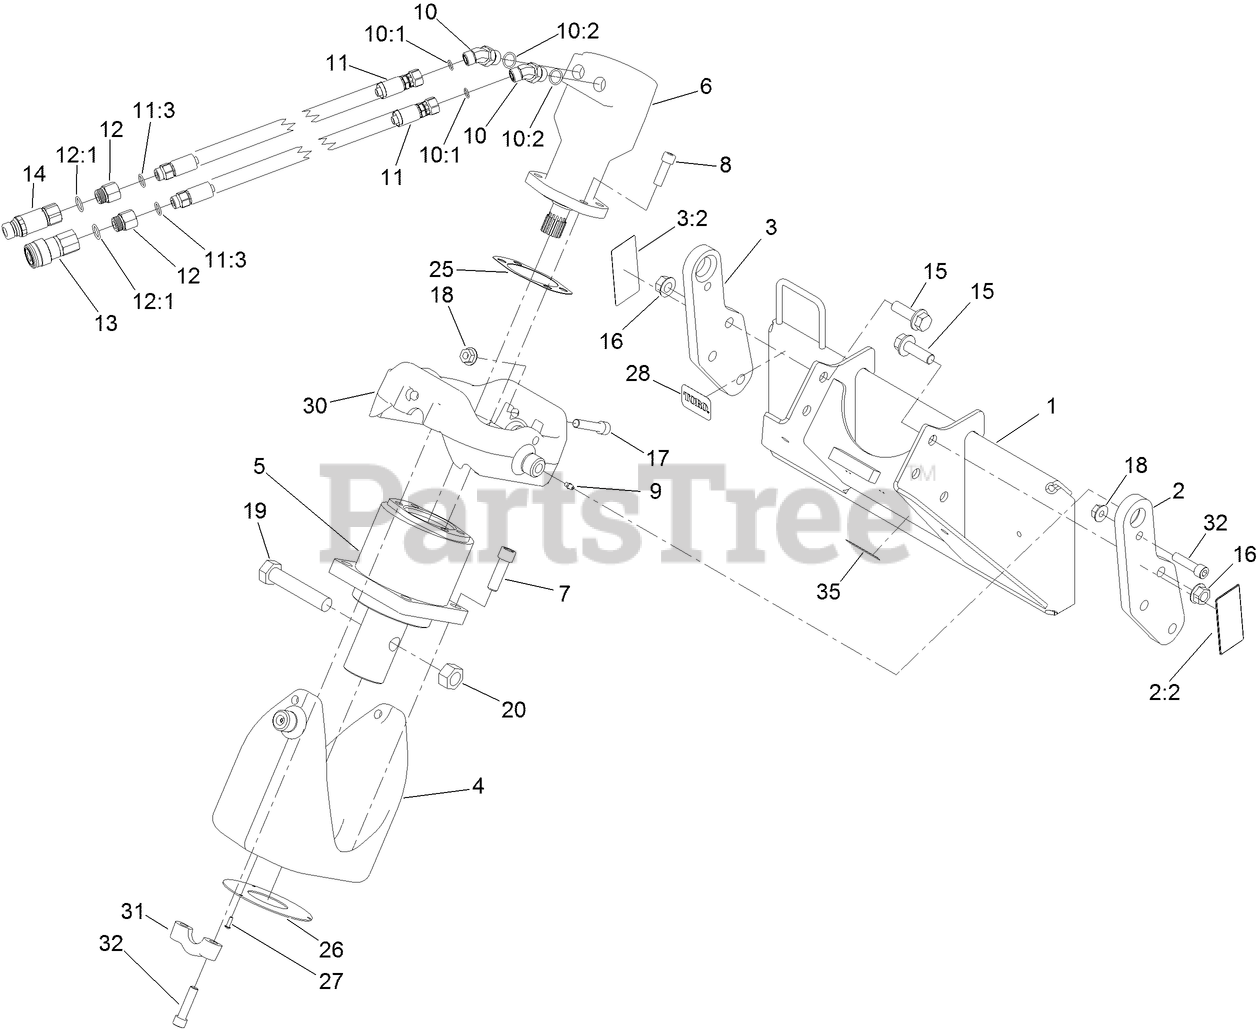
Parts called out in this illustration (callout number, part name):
1	AUGER MOUNT ASM
2	PLATE-PIVOT, LH
2:2	DECAL-DANGER
3	PLATE-PIVOT, RH
3:2	DECAL-DANGER
4	YOKE-AUGERHEAD
5	PLANETARY DRIVE ASM
6	HYD MOTOR ASM
7	SCREW-HSH
8	SCREW-HSH
9	FITTING-GREASE
10	FITTING-HYD, 45 DEG
10:1	O-RING
10:2	O-RING
11	HYD HOSE ASM
11:3	O-RING
12	ADAPTER-HYD
12:1	O-RING
13	COUPLER-FACE, FLUSH
14	NIPPLE-CONNECT, PRESSURE
16	NUT-FLANGE
17	SCREW-HSH
18	NUT-HHF
19	SCREW
20	NUT-HEX
25	GASKET
26	PLATE-GUARD, SEAL
27	SCREW-HSBH
28	DECAL
30	SWIVEL-AUGERHEAD
31	LUG-SWIVEL
32	SCREW-HSH
35	DECAL-WARNING
